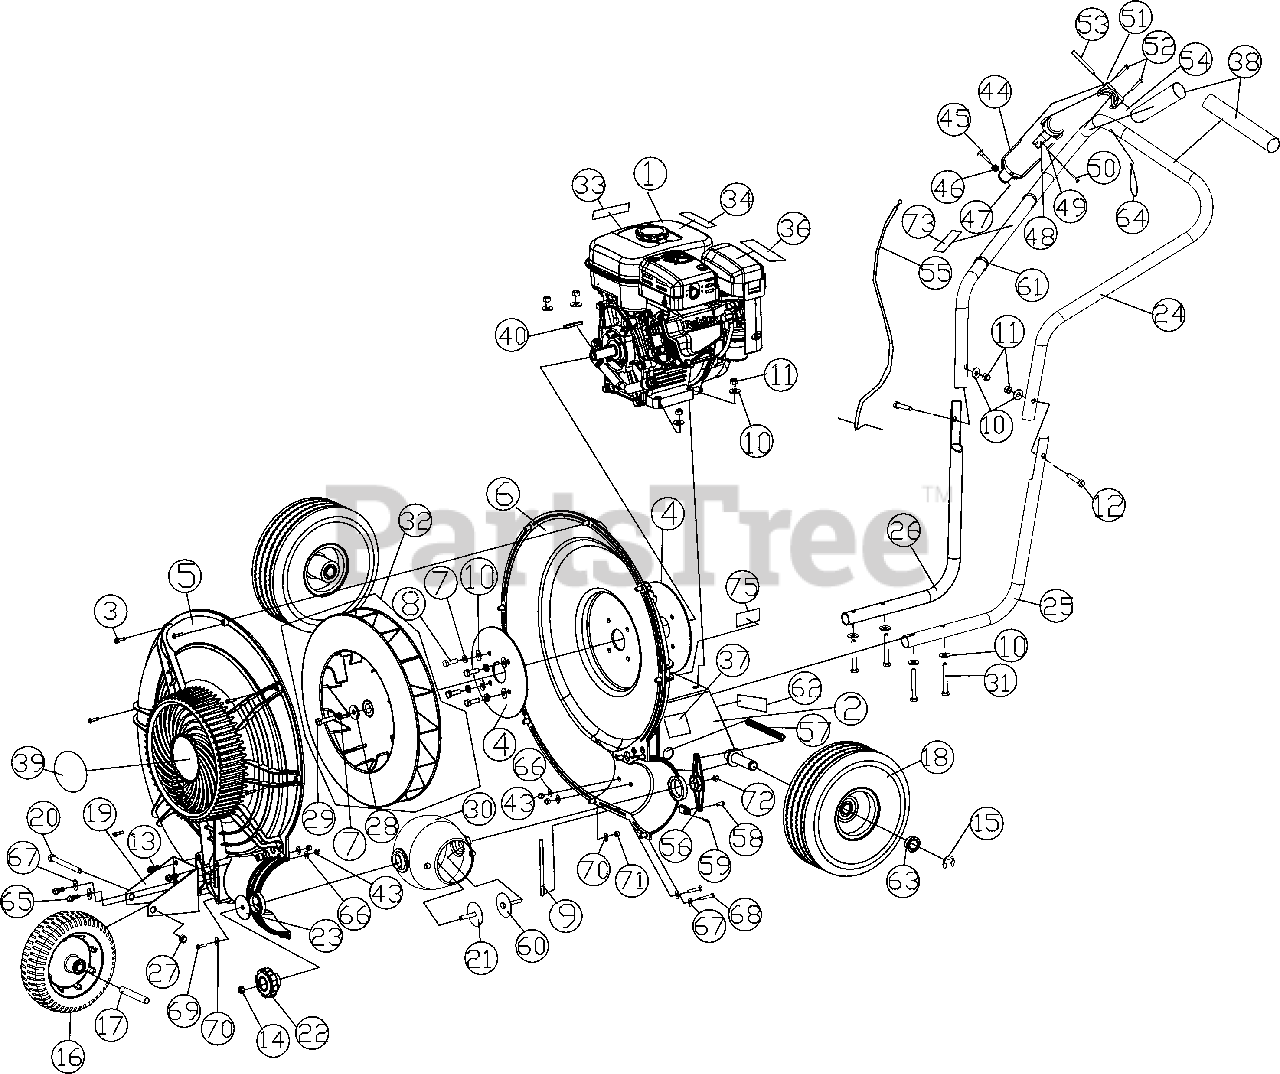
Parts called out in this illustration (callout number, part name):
1	ENGINE 6 HP HONDA
2	BASE ENGINE WA
3	SCREW PLASTITE #8-16 X 3/4" HWH
4	PLATE REINFORCE HOUSING
5	HOUSING FRONT MOLDED
6	HOUSING BACK MOLDED
7	WASHER LOCK 5/16 ST MED
8	SCREW CAP 5/16-24 X 1" GR. 5 ZP
9	ROD HAND STOP
10	WASHER 5/16 FLATWASHER Z/P
11	NYLON INSERT LOCKNUT 5/16-18
12	SCREWCAP 5/16-18 X 1.75 ZP
13	SCREW PLASTITE 1/4-10 X 3/4 HWH
14	NUT LOCK 5/16-18 LT WT TH ZP
15	RING RETAINING 3/4
16	WHEEL 8" X 0.5
17	SPACER FRONT AXLE
18	WHEEL ASSY 10"
19	FRONT WHEEL BRACKET
20	SCREWCAP 3/8-16 X 3 3/4 HCS ZP
21	WASHER W/BOLT WA
22	KNOB 5/16-18 X 5/8 FLUTED
23	WASHER EXTENSION
24	HANDLE UPPER
25	HANDLE LOWER LH
26	HANDLE LOWER RH
27	NUT LOCK 3/8-16 LT WT THIN ZP
28	WASHER 1.125 OD X 0.344 ID X 10 GA.
29	SCREWCAP 5/16-24 X 1 1/2 GR 8 24-28 Ft. lbs. (33-38 N.m.)
30	DIRECTOR CONE 3.5"
31	SCREWCAP 5/16-18 X 2 1/2
32	IMPELLER ASSEMBLY 16"
33	LABEL SPARK ARRESTOR
34	LABEL WARNING FUEL EN/SP
36	LABEL SAFETY PROTECT READ MANUAL
37	LABEL DANGER FLYING DEBRIS
38	GRIP 1" ID x 13"
39	LABEL LOGO SMALL FRAME
40	Key 3/16" SQ x 1 3/4
43	NUT LOCK 1/4"-20 HEX ZP
44	HANDLE DIVERTER FORCE
45	PIN LATCH DIVERTER
46	SPRING COMPRESSION 0.281 X 0.88
47	RING RETAINING .122 DIA
48	SADDLE LOWER DIVERTER
49	PLATE LOCK DIVERTER
50	SCREW PLASTITE #6-19 X 5/8"
51	SADDLE UPPER DIVERTER
52	SCREW PLASTITE #10-14 X 1"
53	PIN PIVOT DIVERTER CONTROL
54	RING RETAINING 5/16
55	CABLE ASSY
56	DIVERTER PIVOT ADAPTOR
57	SPRING EXTENSION 0.468 X 5.25
58	PIN CLEVIS 1/4 X 3/4
59	.051 X 3/4" HITCH PIN CLIP
60	ADAPTOR MOUNT WA
62	LABEL VIBRATION WARNING
63	FORCE WHEEL BEARING .751 ID
64	ELASTIC LOOP BLACK 5.5"
65	SCREWCAP 1/4-20 X 1 1/4" HCS ZP
66	FENDER WASHER 5/16
67	WASHER 1/4" SAE
68	SCREWCAP 1/4"-20 1 1/2" HCS ZP
69	SCREWCAP #10-24 X 1 1/4" HWH ZP
70	WASHER #10 SAE
71	NUT LOCK LT #10 - 24 HEX
72	NUT LOCK 1/4"-20 2 WAY
73	LABEL AIM AND SHOOT
75	LABEL MADE IN U.S.A.
